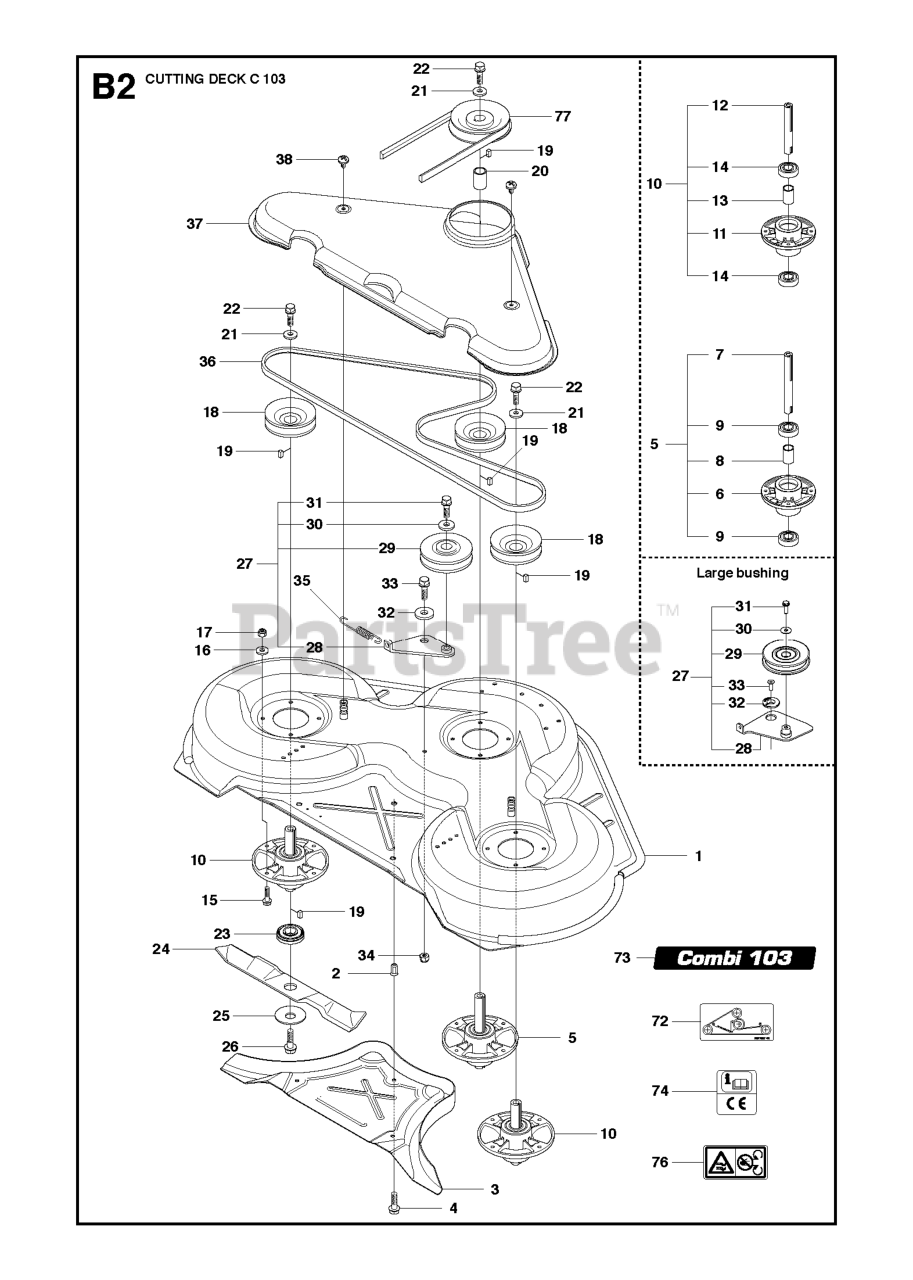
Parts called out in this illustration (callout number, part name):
1	CUTTING DECK RIDER
5	BLADE HOUSING ASSY
6	BEARING HOUSING
8	SPACING SLEEVE
10	BLADE HOUSING ASSY
11	BEARING HOUSING
13	SPACING SLEEVE
16	WASHER BRB 8.4X17
17	LOCKNUT M8
25	WASHER
27	BELT TENSIONER ASSY KIT
27	BELT TENSIONER ASSY
28	BELT TENSIONING ARM
31	BOLT
32	WASHER SHOULDER ASSY
32	WASHER
33	SCREW
34	LOCKNUT M8
